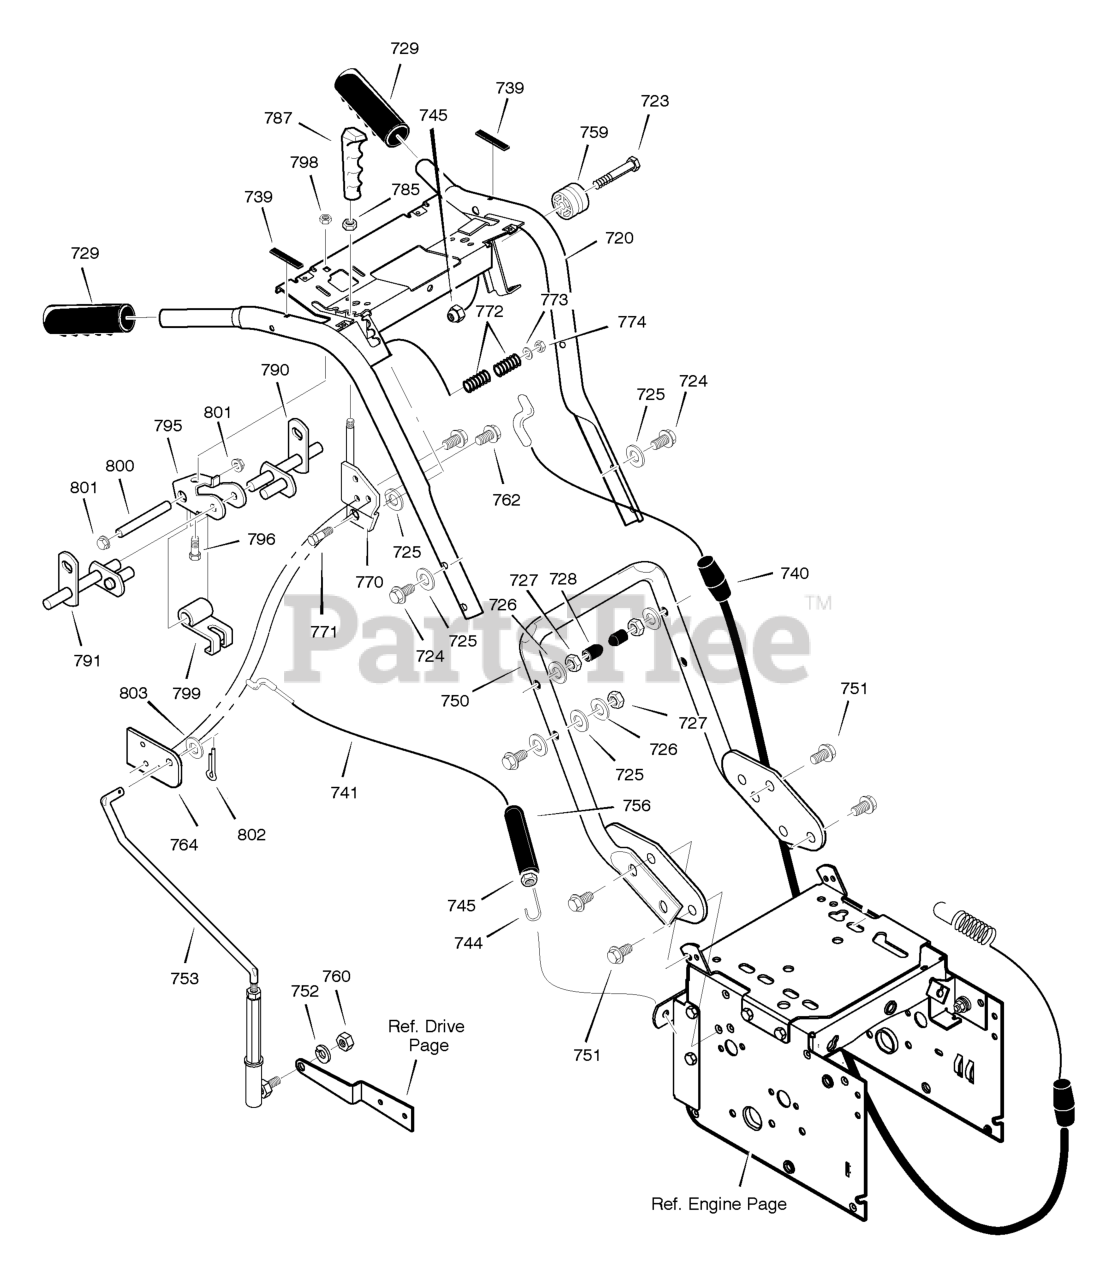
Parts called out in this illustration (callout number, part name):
720	ASSY., HANDLE
724	SCREW
725	WASHER
726	WASHER
728	STOP, PLASTIC
729	GRIP, HANDLE
739	BUMPER
740	CABLE, DRIVE
741	CABLE, AUGER
744	SPRING, AUGER CLUTCH
745	NUT, HEX -1/4-20
750	HANDLE, LOWER
751	SCREW
753	ASSEMBLY, ROD
756	BOOT, SPRING
759	SPOOL, CABLE
760	NUT, 5/16-24
762	SCREW 1/4-20X0.63
764	BRACKET, CONTROL
770	BRACKET, SHIFT
771	SCREW
773	WASHER
774	NUT, HEX, 3/8-16
785	NUT, HEX, 3/8-16
787	KNOB, SHIFT
790	ROD, ASSY LH
791	ROD, ASSY RH
795	BRACKET, CAM
796	SCREW
798	NUT, NYLOCK
799	CAM LOCK
800	PIN, SPRING PIVOT
801	NUT, PUSH ON
802	PIN, COTTER
803	WASHER
